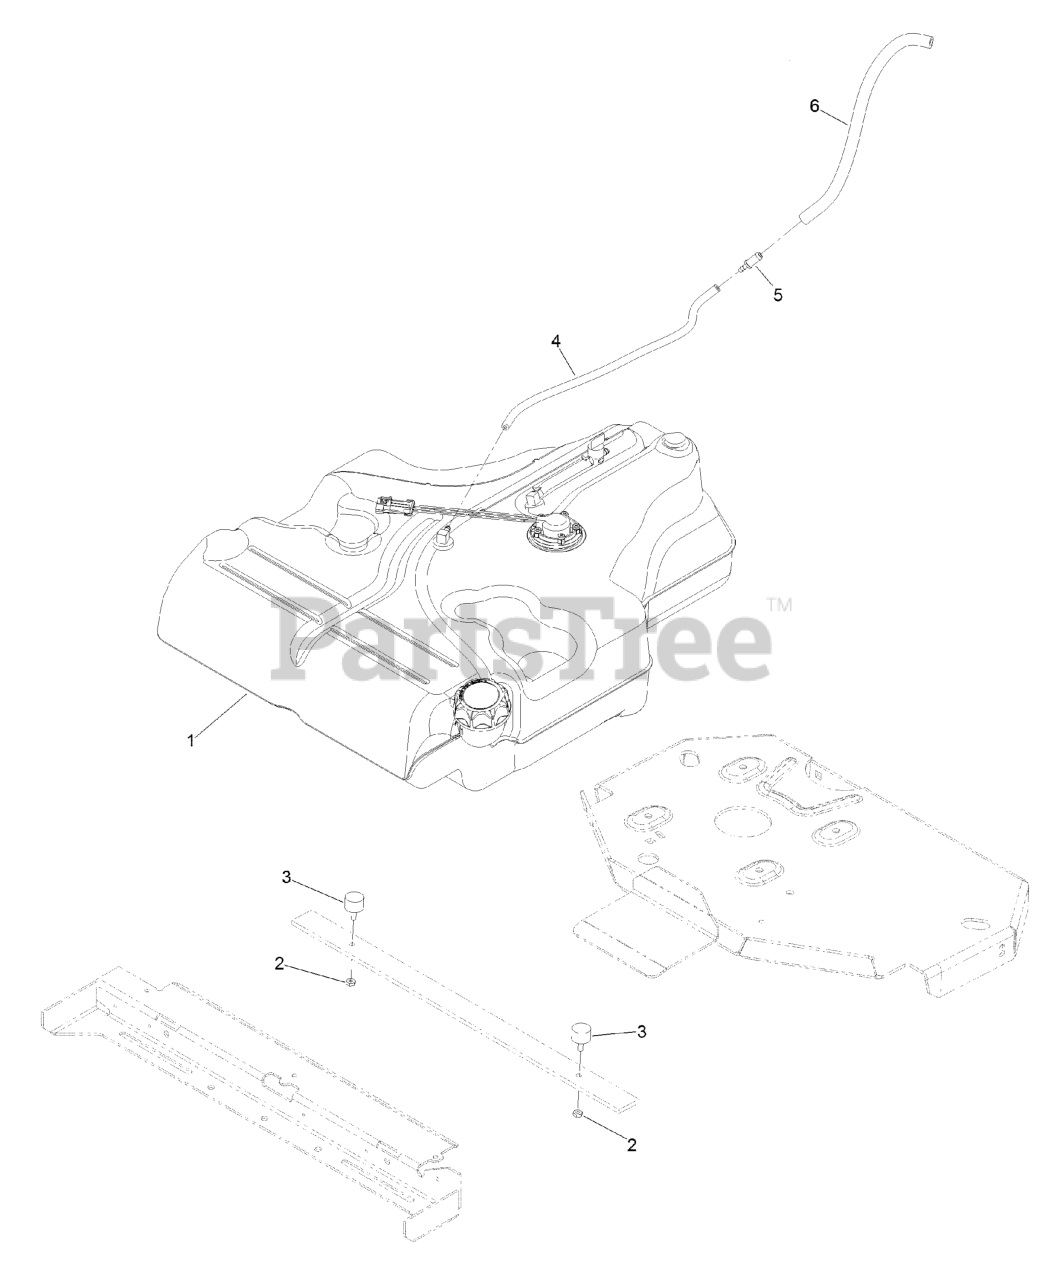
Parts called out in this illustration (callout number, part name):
1	FUEL TANK ASM
2	NUT-JAM
19	HOSE-FUEL
21	FITTING-STRAIGHT
22	HOSE-FUEL
